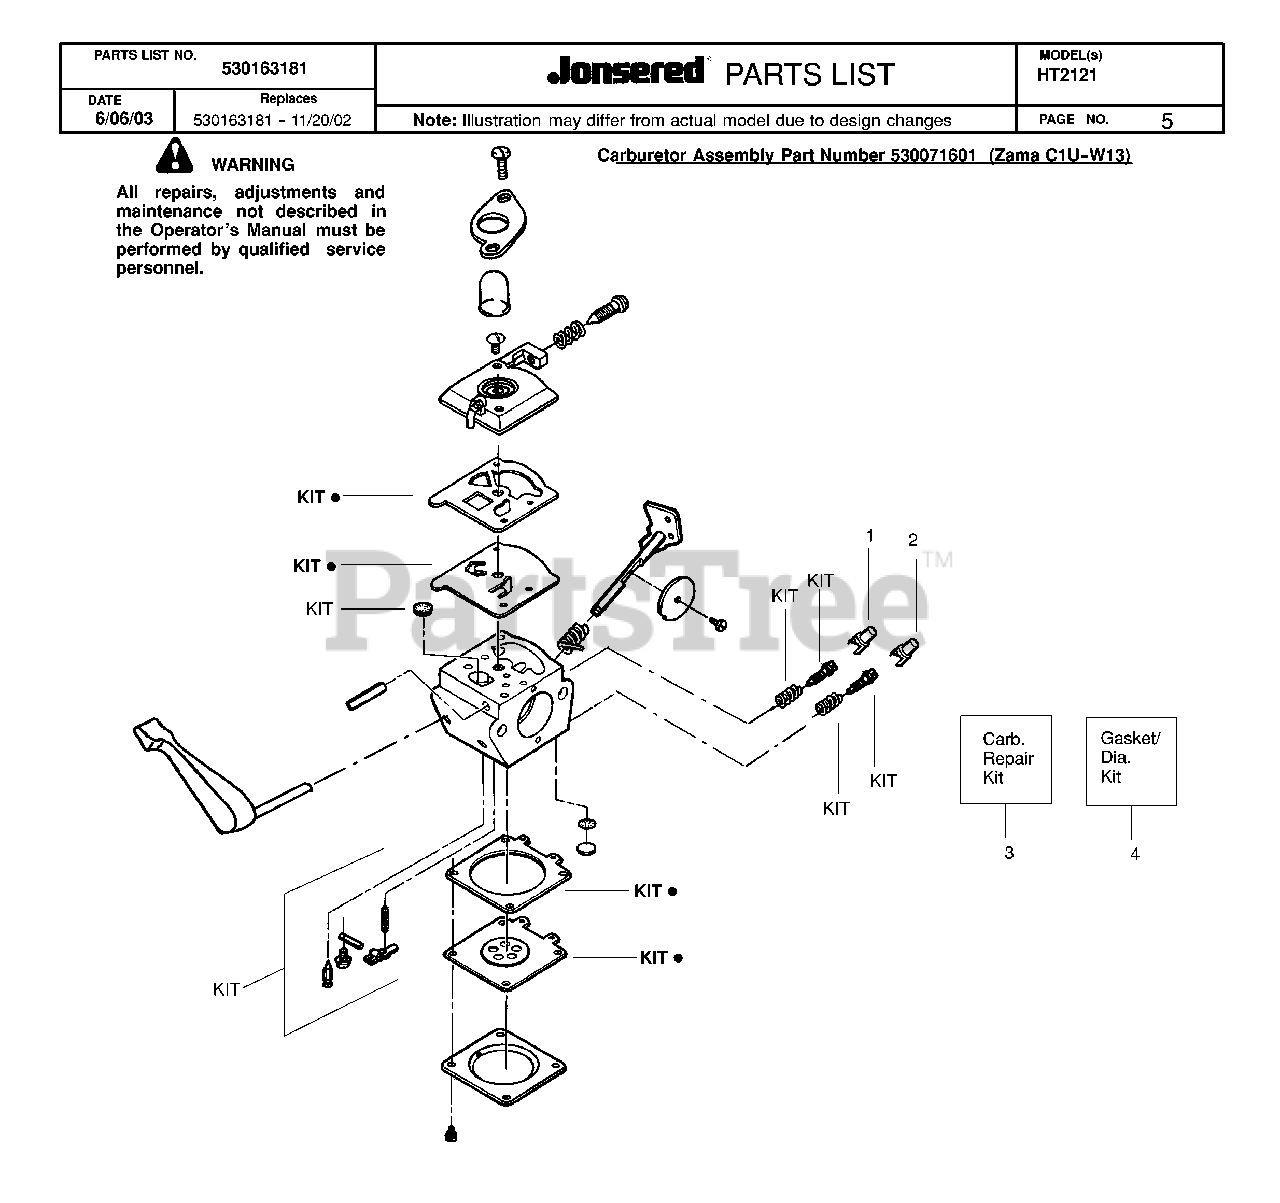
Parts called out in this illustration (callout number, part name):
1	LIMITER CAP-LOW
2	LIMITER CAP-HIGH
4	GASKET/DIAPHRAGHM KIT
